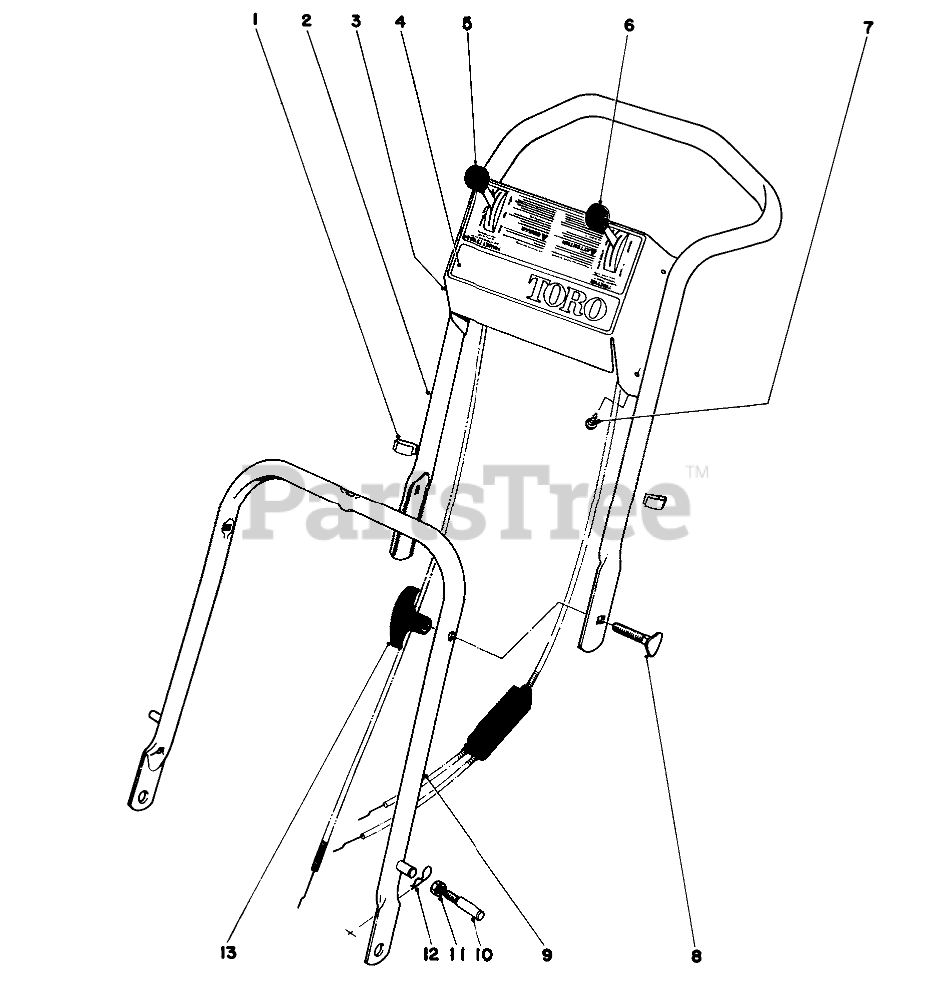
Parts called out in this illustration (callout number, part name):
1	BOWDEN CLIP
2	UPPER HANDLE
3	Control Plate
4	Decal-Control Plate (French & Dutch)
5	Control Throttle
6	Traction Control
7	SCREW-HWHTF
8	HANDLE SCREW
9	Lower Handle
10	HANDLE PIN
11	Nut
12	PIN-COTTER, HAIR
